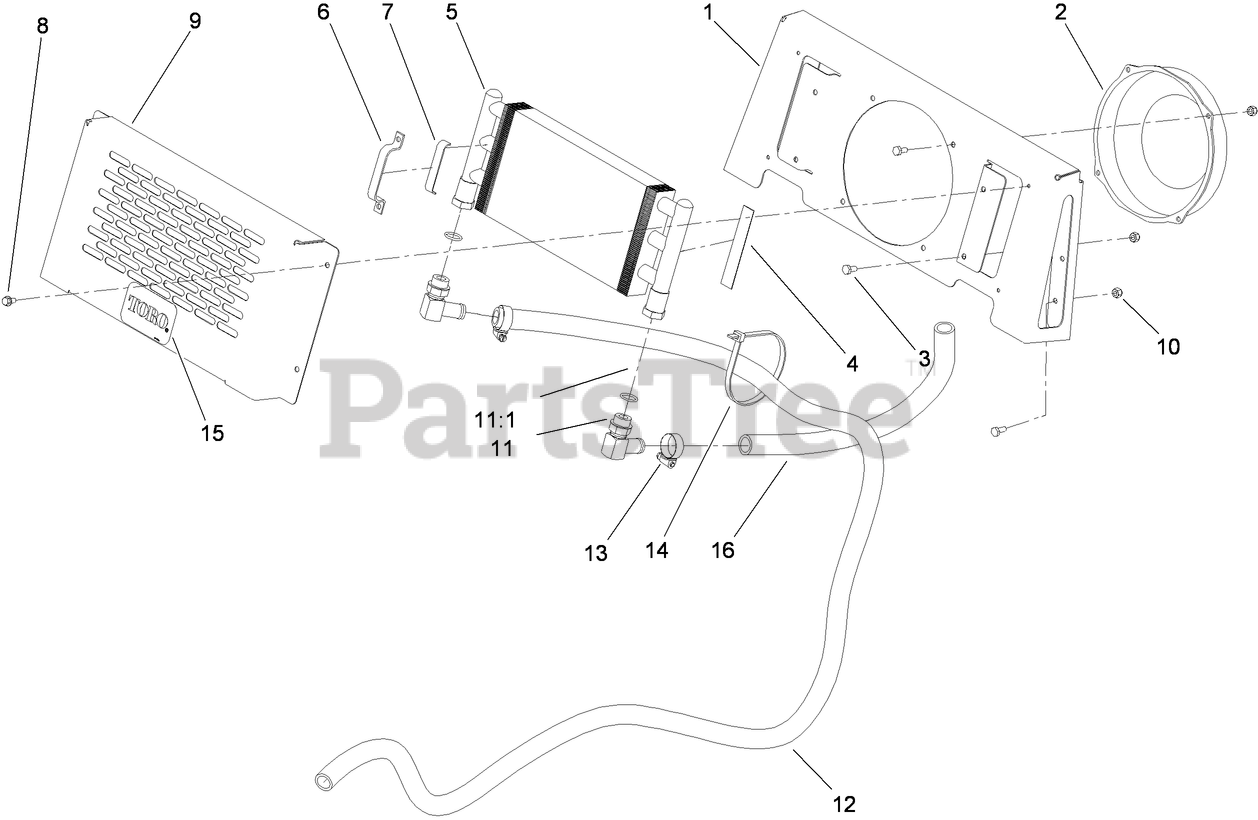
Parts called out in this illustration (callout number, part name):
1	BRACKET-FAN
3	SCREW-HH
4	PAD-FOOTREST
5	EXCHANGER-HEAT
6	SUPPORT-COOLER
7	PAD-SUPPORT
8	SCREW-THD FRM,HWH
9	BRACKET-COVER, COOLER
10	NUT-LOCK, NI
11	FITTING
11:1	O-RING
12	HOSE-RETURN
13	CLAMP-HOSE
14	TIE-CABLE
15	DECAL
16	HOSE-COOLER
